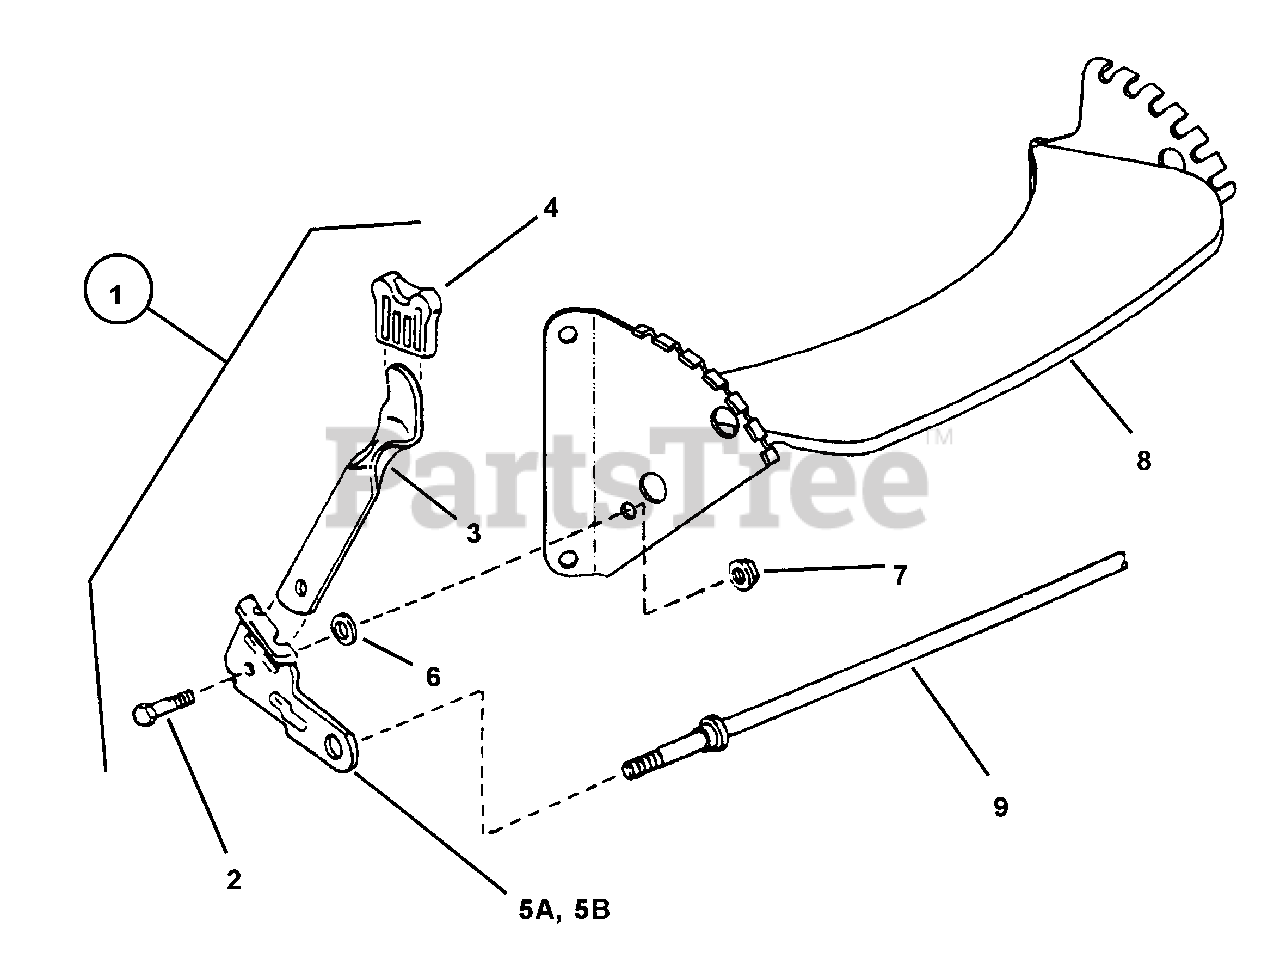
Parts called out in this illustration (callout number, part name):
1	ASSEMBLY, Arm Right Wheel
2	BOLT, 5/16-18 x 3/4" Shoulder
3	LATCH, Height
4	GRIP, Latch
5A	ARM, Right Wheel (Round Hole)
6	RETAINER, 5/16" Bolt
7	NUT, 5/16-18 Hex Flange Lock, Grade 5
8	BRACKET, Front Wheel
9	AXLE
